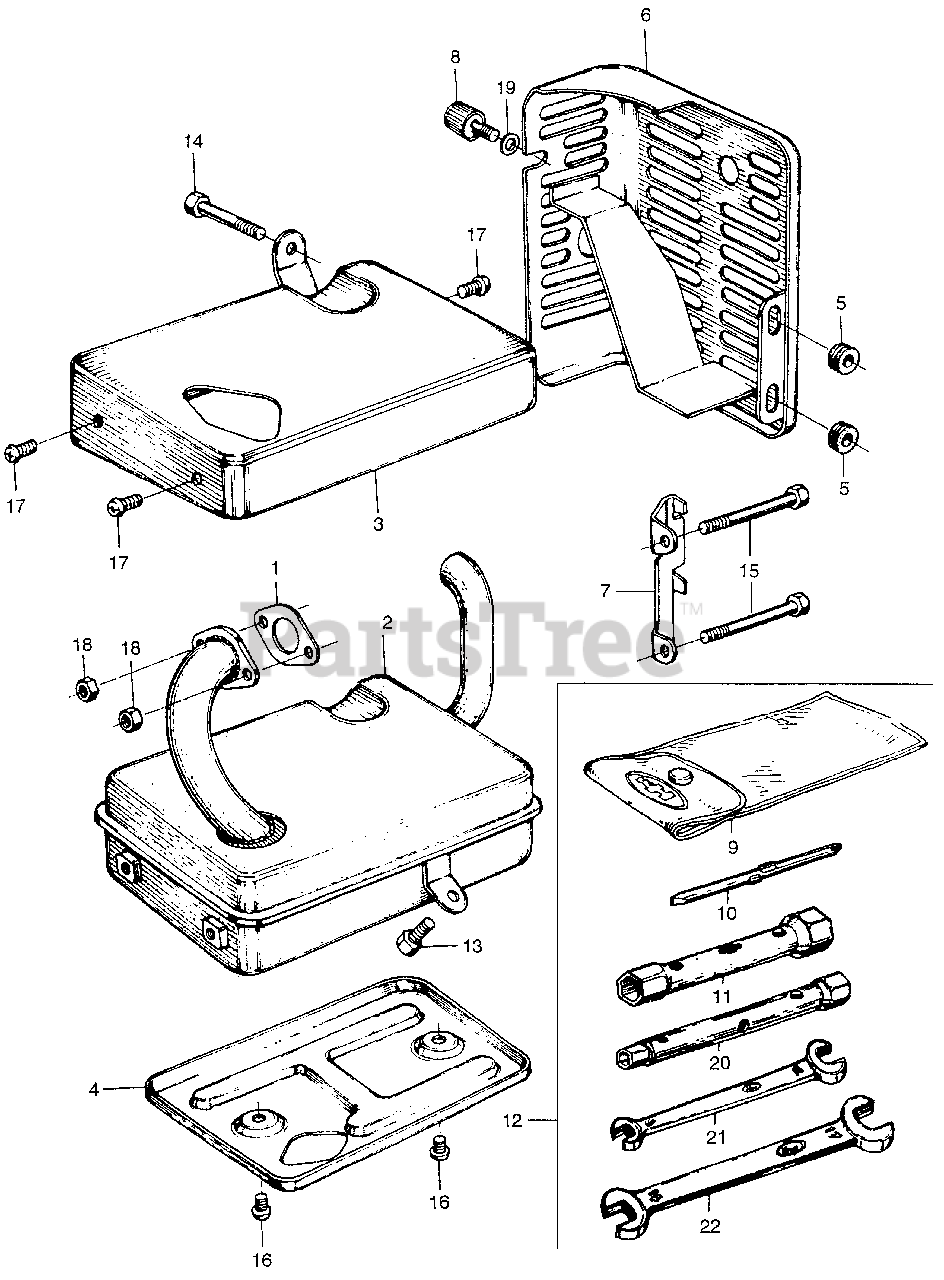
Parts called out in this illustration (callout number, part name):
1	GASKET, EX. PIPE (NOT AVAILABLE)
3	PROTECTOR A
4	PROTECTOR B (NOT AVAILABLE)
5	GROMMET A, SIDE COVER (NOT AVAILABLE)
6	COVER, R. SIDE *R8* (BRIGHT RED) (NOT AVAILABLE)
7	STAY, SIDE COVER
8	LATCH, SIDE COVER
11	WRENCH, SPARK PLUG (NOT AVAILABLE)
12	TOOL ASSY. (N/A: SEE ASSEMBLY)
13	BOLT, HEX. (6X12)
14	BOLT, HEX. (6X45)
15	BOLT, HEX. (6X25)
16	SCREW, PAN (5X6)
17	SCREW, PAN (5X6)
18	NUT, HEX. (6MM)
19	WASHER, PLAIN (6MM)
20	WRENCH (8X12) (OPEN END)
21	WRENCH (10X12) (OPEN END)
22	WRENCH (14X17) (OPEN END)
